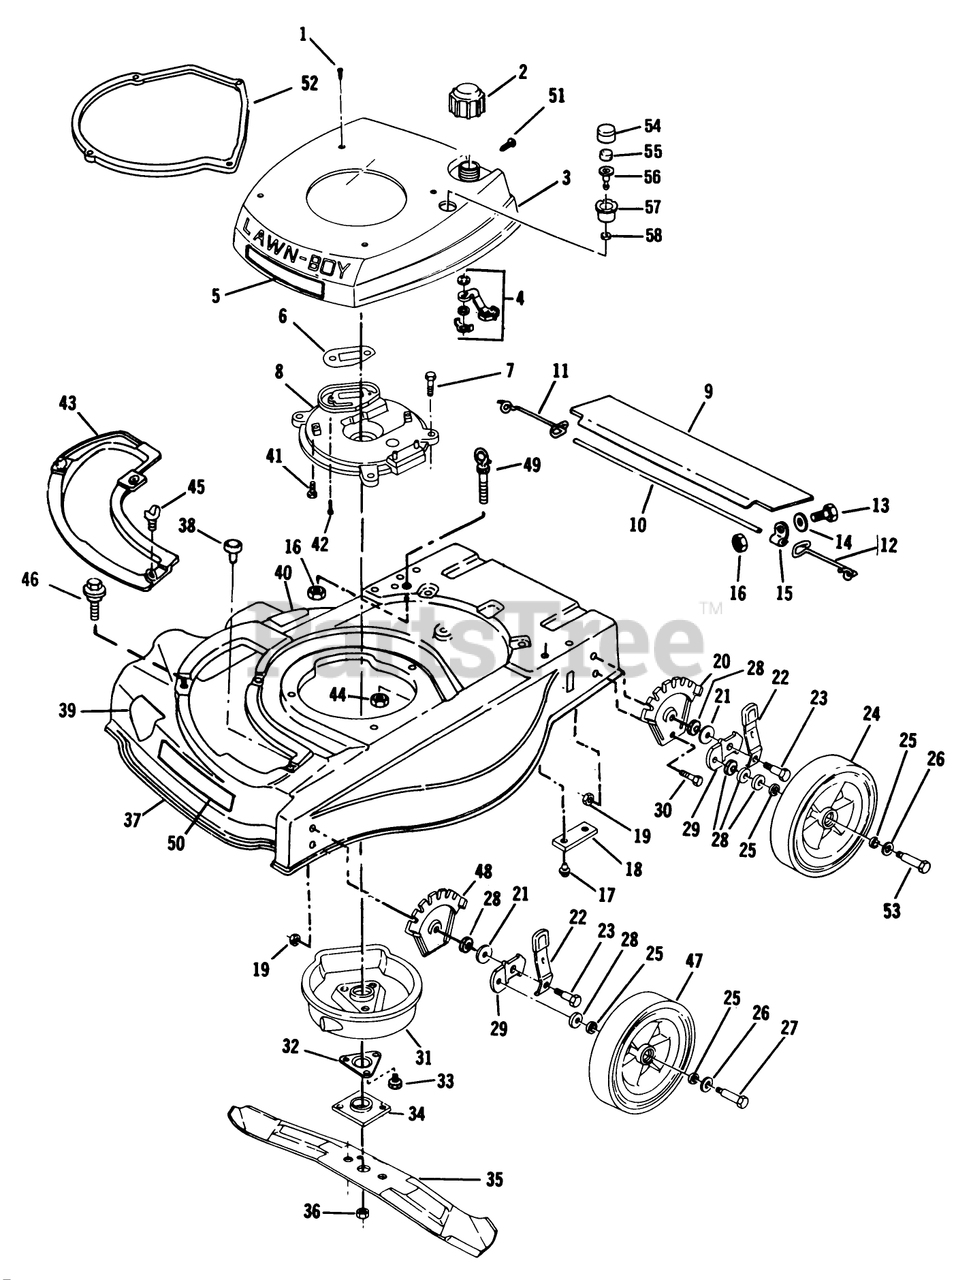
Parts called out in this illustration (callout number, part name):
1	SCREW LAWRENCE
2	FUEL CAP & INSERT
7	SCREW-HH
8	PLATE,MUFFLER F
10	ROD T/SHIELD ADV WIRE
11	SPRING;TRAILING SHIELD RH
12	SPRIG T/SHLD ASOC
14	WASHER F
15	CLAMP ROD KMC
16	LOCKNUT E
17	SCREW
19	LOCKNUT
21	WASHER
22	KNOB & SPRING
23	BOLT
25	WASHER
26	SPACER
27	BOLT WHEEL
28	WASHER WROUGHT
32	SUPPORT F
33	SCREW
34	PLATE AND COLLAR ASM
36	NUT-BLADE
42	SCREW V
44	NUT-LOCK F
45	WING SCREW LAWRE
47	WHEEL & TIRE KIT
48	PLATE HGT ADJ TRO
49	BOLT-EYE
51	SCREW S
55	FILTER S
56	BASE P'MERBULB S
57	CUP PRIMER PL
